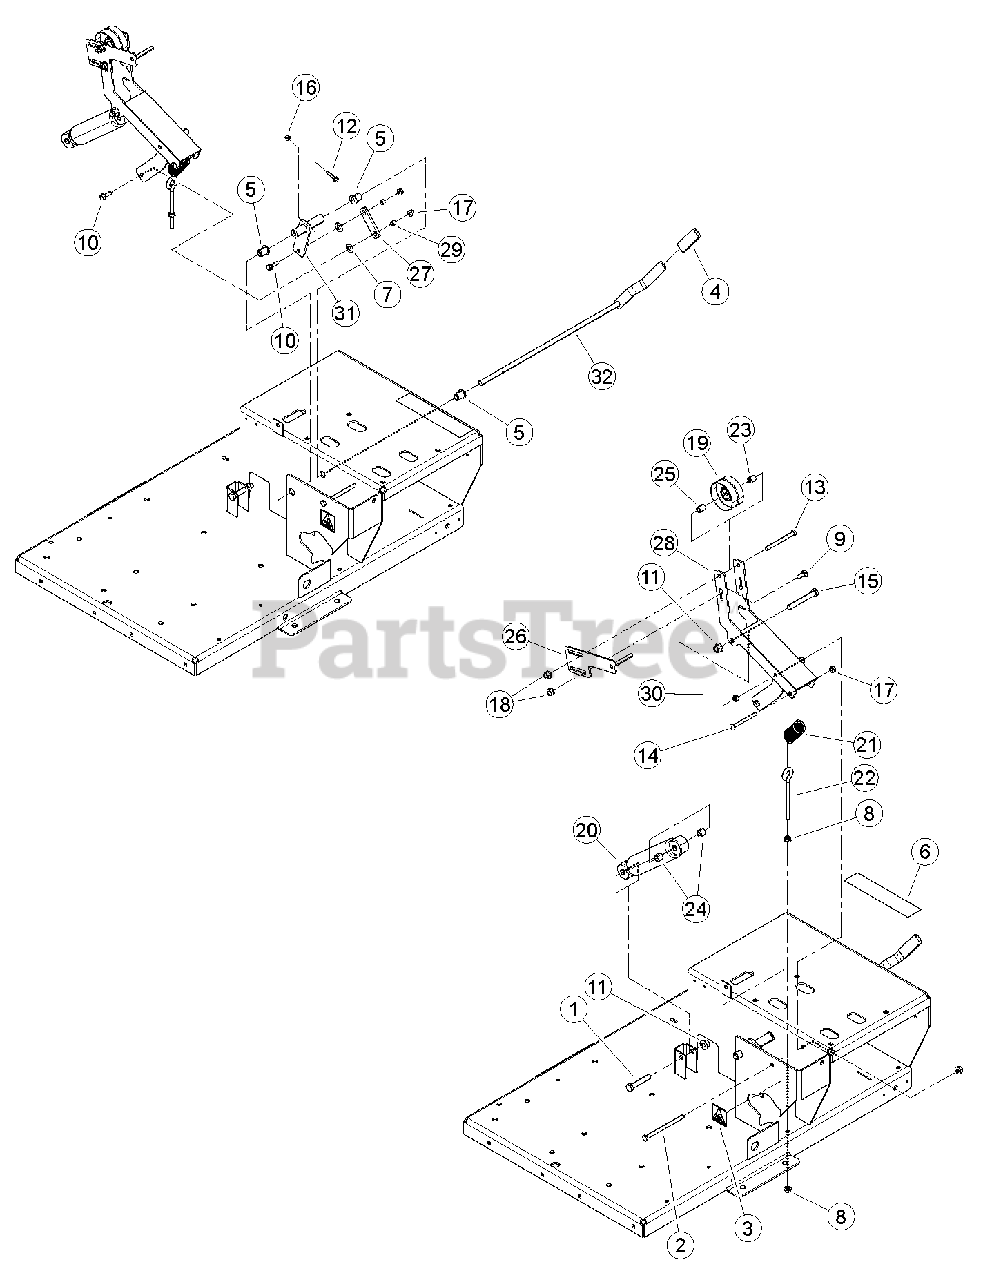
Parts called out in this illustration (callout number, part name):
1	BOLT, 1/2 X 2-3/4 HEX GR5 ZP
2	BOLT, 3/8 X 5-1/2 HEX GR5 ZP
3	DECAL, SHIELD DANGER ISO
4	GRIP, CLUTCH HANDLE
5	BUSHING, 1/2 X 1 FLANGE LUBE
6	DECAL, CHIPPER ENGAGEMENT
7	WASHER, 1/2 INCH NYLON
8	NUT, 3/8-16 SERRATED FLANGE
9	BOLT, 3/8-16 X 1 GR5 CRG
10	BOLT, 5/16 X 1 FLANGE NC
11	NUT, 1/2-13 NYLOCK FLANGE
12	BOLT, 1/4 X 1-1/4 FLANGE NC
13	BOLT, 3/8 X 4" HHCS GR5 NC ZP
14	BOLT, 5/16 X 3-1/2 GR5 CRG ZP
15	BOLT, 1/2 X 3-3/4 HHCS GR5 NC ZP
16	NUT, 1/4-20 NYLOCK FLANGE
17	NUT, 5/16-18 NYLOCK FLANGE
18	NUT, 3/8-16 NYLOCK FLANGE
19	PULLEY, 3-1/4 FLAT IDLER
20	ABSORBER, IDLER SHOCK
21	SPRING, 1.25 OD X 3.50 LG X .148 WD
22	EYEBOLT, 3/8" X 5" LG 4-1/4 THD ZP
23	SPACER, .63 X .63 PULLEY
24	SPACER, .75 X .59
25	SPACER, 5/8 OD X 11 GA X .760
26	WELDMENT, PIVOT ROD
27	PLATE, CONNECTING ARM
28	WELDMENT, IDLE ARM
29	SPACER, 1/2" OD X 14GA WA
30	SPACER, 5/8" OD X 3/8" ID X 0.28"
31	WELDMENT, PIVOT ARM
32	WELDMENT, HANDLE
